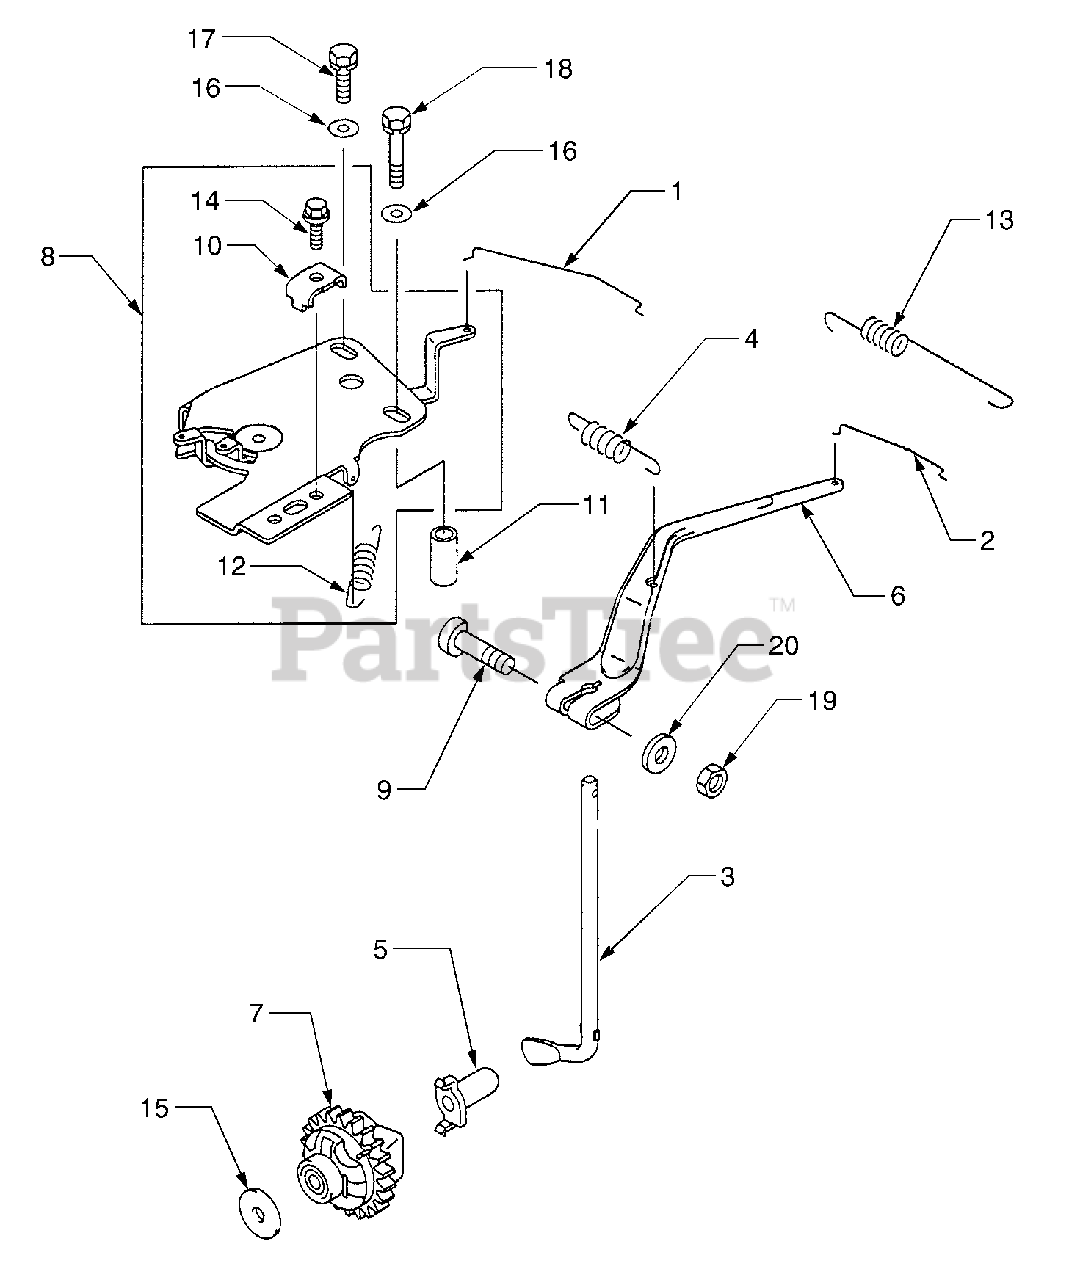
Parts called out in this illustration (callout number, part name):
4	Spring, Governor
6	Arm, Governor
7	Governor Assembly
8	Panel, Control
11	Collar, 6.8 x 10 x 20.5
13	Spring
17	Bolt, 6 x 16
18	Bolt, 6 x 35
19	Nut, Hex
20	Washer, Plain
